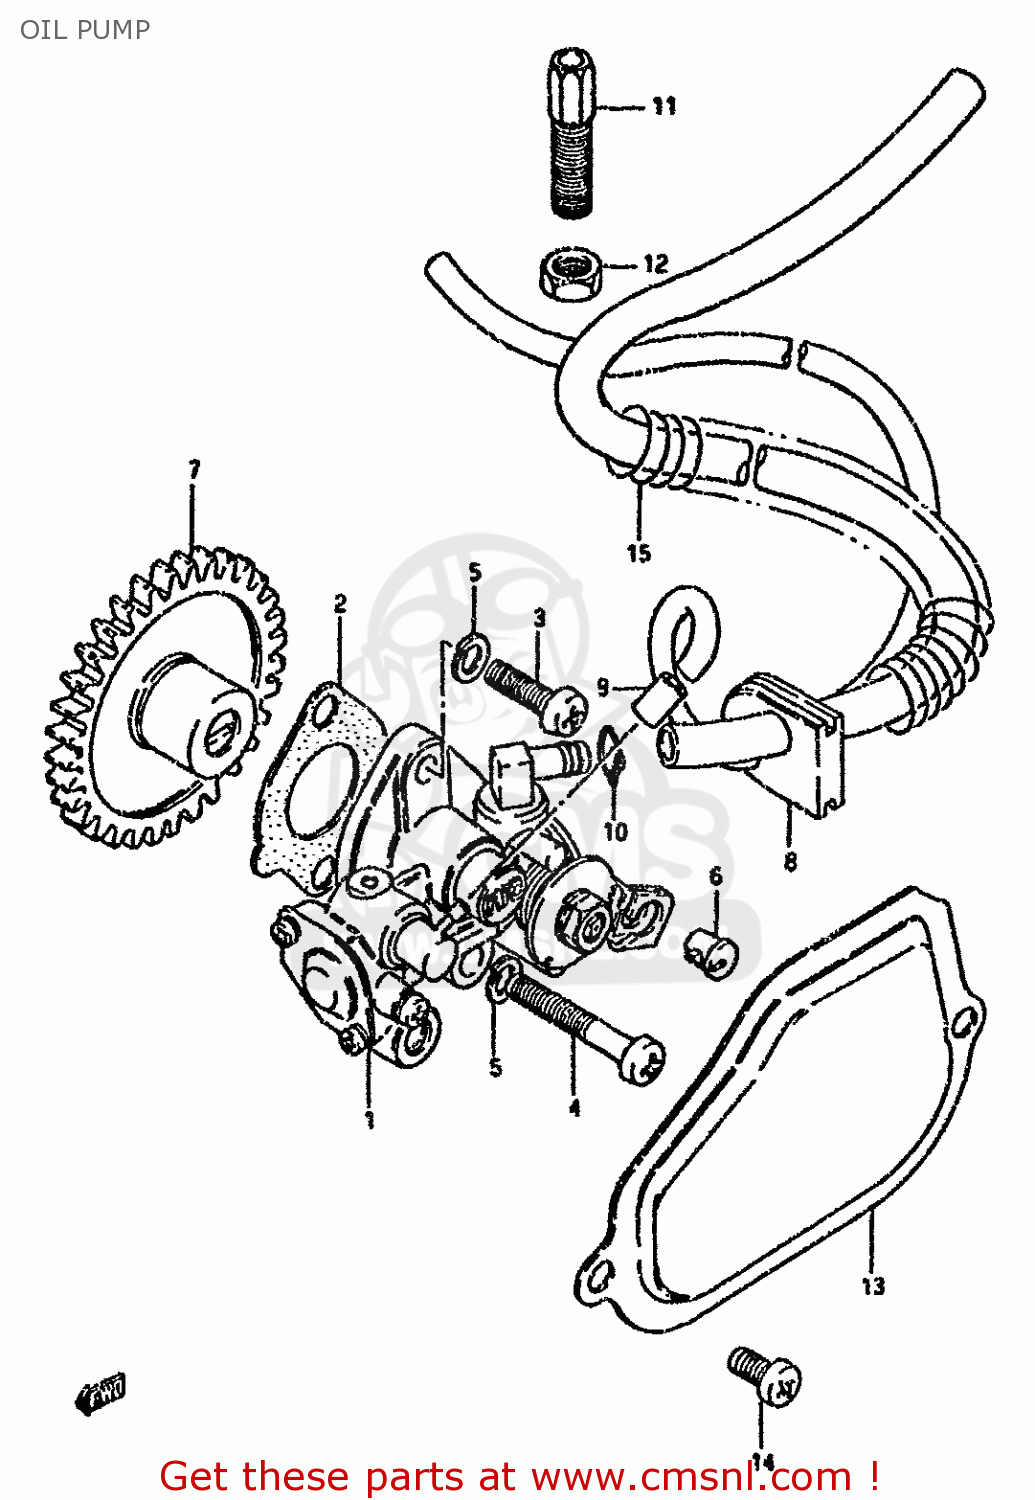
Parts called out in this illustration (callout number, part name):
1	PUMP ASSY,OIL
2	GASKET,OIL PUMP (NAS)
3	SCREW
4	SCREW
5	WASHER,LOCK
6	TERMINAL,CABLE
7	GEAR,OIL PUMP DRIVEN(NT:36)
8	HOSE SET,OIL NO.2
9	CLIP
10	CLIP
11	BOLT
12	NUT
13	CAP,OIL PUMP INSPECTION
14	SCREW
15	SPRING
